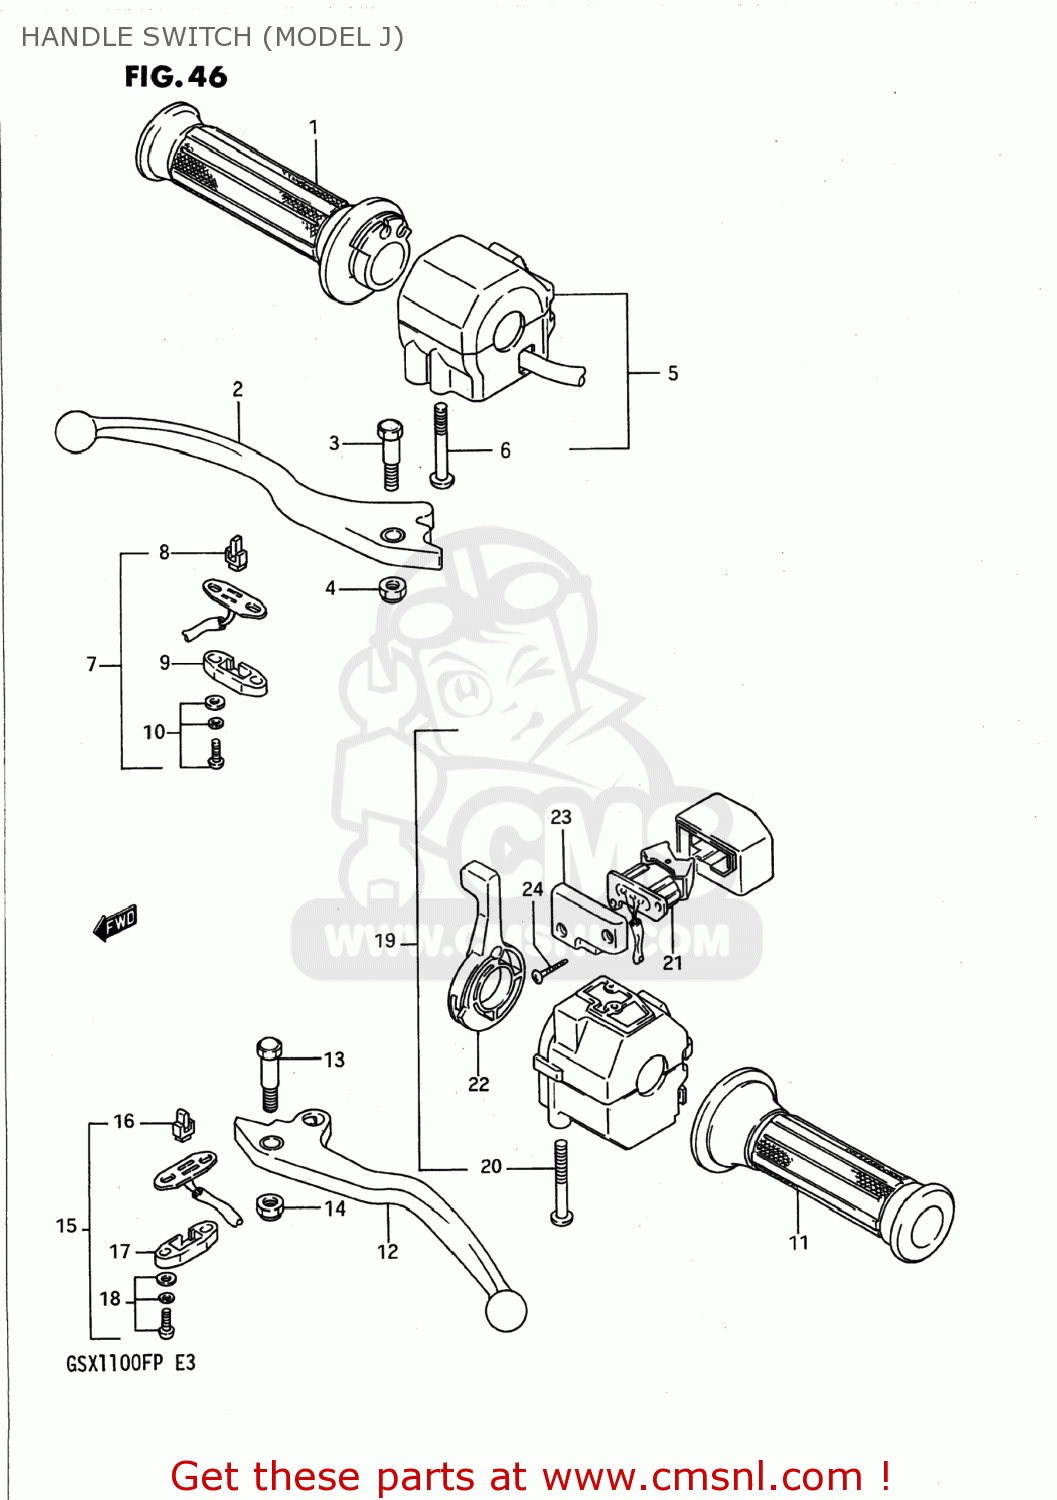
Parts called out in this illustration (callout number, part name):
1	GRIP,THROTTLE
2	LEVER,BRAKE
3	BOLT,LEVER
4	NUT
5	SWITCH ASSEMBLY,HANDLE,RIGHT
6	SCREW, 5X45
7	SWITCH ASSY,STOP
8	CONTACT,SWITCH
9	COVER,FR BK TERMINAL BASE
10	SCREW
11	GRIP,L
12	LEVER,CLUTCH
13	BOLT,LEVER
14	NUT
15	SWITCH ASSEMBLY,CLUTCH
16	CONTACT,SWITCH
17	COVER,FR BK TERMINAL BASE
18	SCREW
19	SWITCH ASSEMBLY,HANDLE,LEFT
20	SCREW, 5X45
21	SWITCH,SCREEN
22	LVER,CHOKE
23	COVER,SCREEN SWITCH
24	SCREW,SCREEN SWITCH
